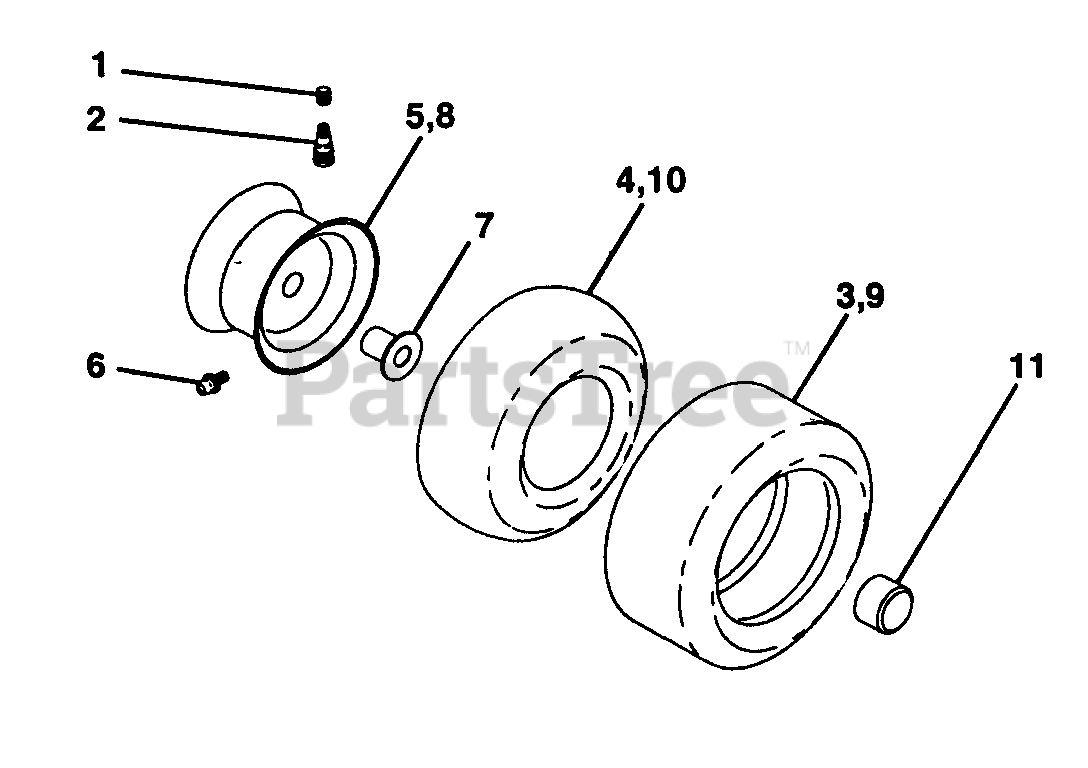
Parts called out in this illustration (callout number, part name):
1	Cap Valve Tire
2	Stem Valve
3	Tire F Ts 15 X 6 0 - 6 Service
4	Tube Front
5	Rim Asm 6"front Silver Service
6	Fitting Grease
7	Bearing Flange
8	Rim Asm 8"rear Silver Service
9	Tire R Ts 20x10-8 C Service
10	Tube Rear
11	Cap Axle Blk 1 50 X 1 00
